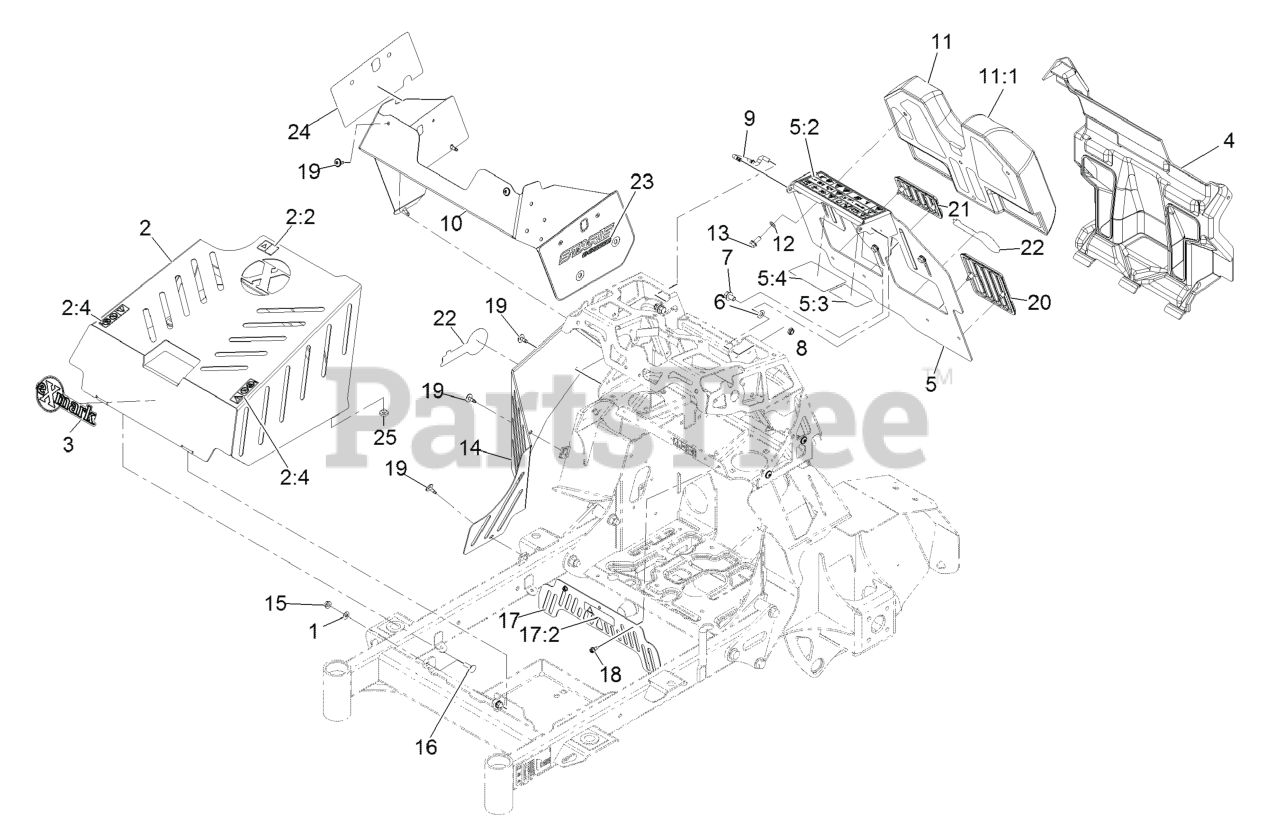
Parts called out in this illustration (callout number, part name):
1	SPACER-NYLON
2	ASM-COVER W DECALS
2:2	DECAL-WARNING
2:4	DECAL-NO STEP/RIDERS
3	DECAL, EXMARK LOGO
4	COVER-REAR STE
5	ASM, PAD BACKING W/ DECALS
5:2	DECAL-WARNING
5:3	DECAL-DRIVE RELEASE
5:4	DECAL-SERVICE AID SM
6	WASHER-THRUST
7	SCREW-HHF
9	ROD, PROP
10	SKIN, TOWER
11	PAD-THIGH
11:1	COVER, PAD
12	WASHER-BELLEVILLE
13	SCREW-HHF
14	COVER, RT SIDE
16	BOLT-CARR
17	ASM, BELT GUARD W/ DECAL
17:2	DECAL-WARNING
18	SCREW-HWH
19	SCREW, TORX
20	PAD, KNEE, LT
21	PAD, KNEE, RT
22	DECAL-EXMARK LOGO
23	DECAL-STARIS LOGO LT
24	Decal-Staris Logo Rt
